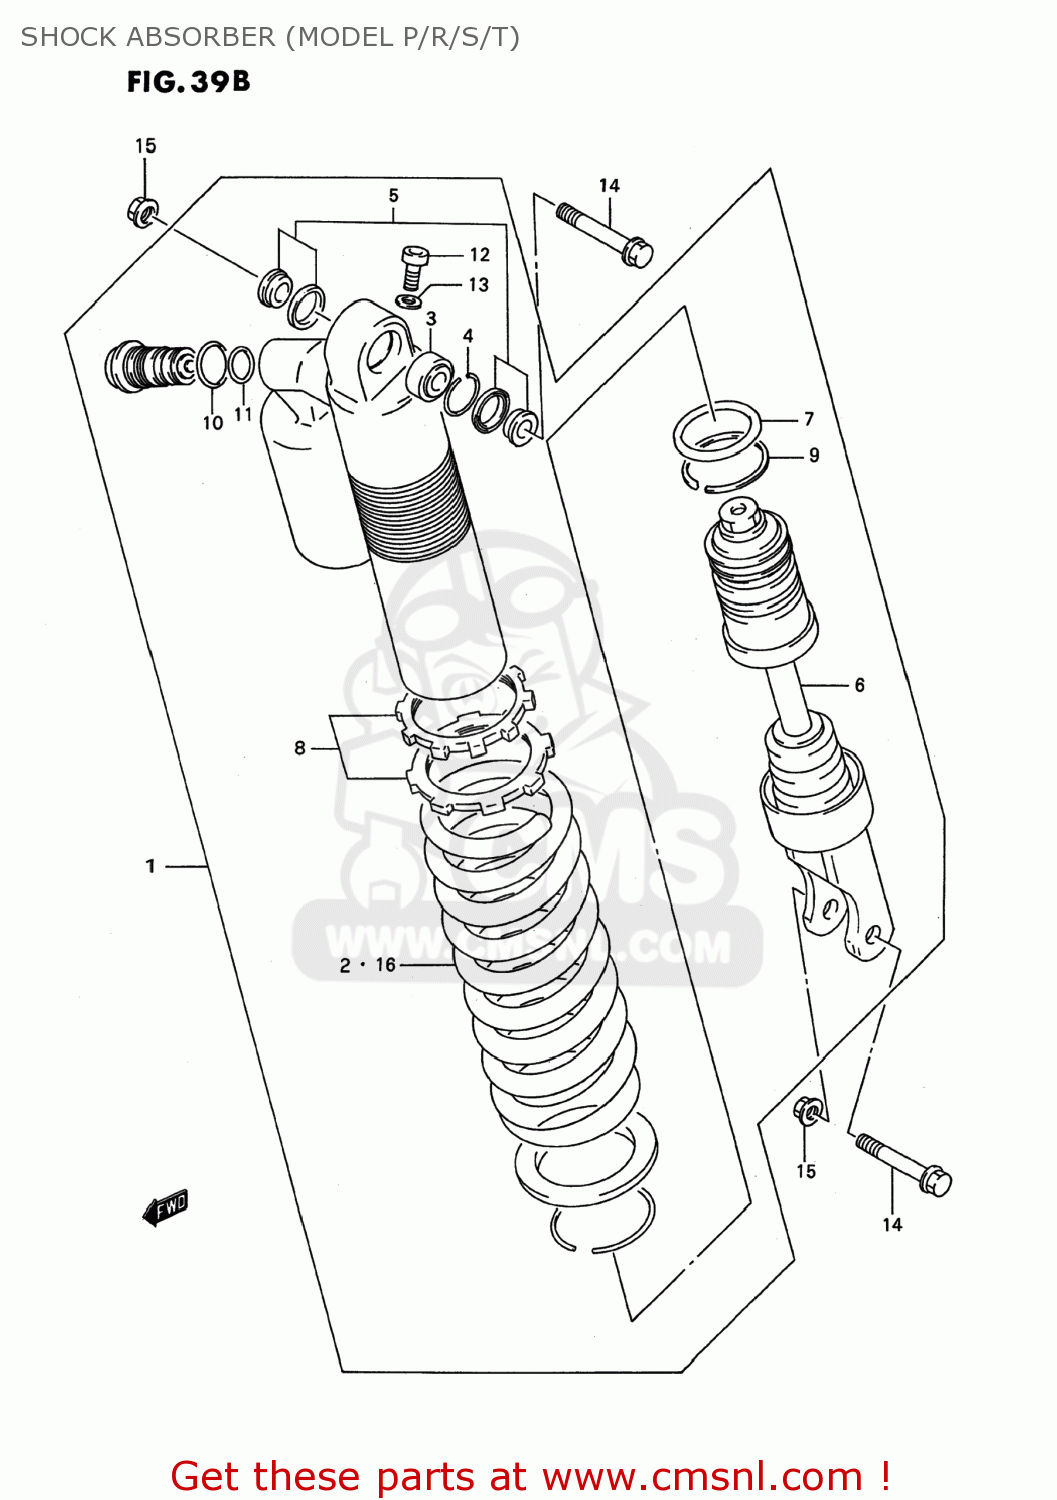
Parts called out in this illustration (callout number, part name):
1	ABSORBER ASSEMBLY,REAR SHOCK
2	SPRING
3	BEARING,RR CUSHION LEVER RR
4	RING,STOPPER
5	COLLAR SET,RR SHOCK ABSORBER
6	ROD,PISTON
7	O RING
8	ADJUSTER SET,SHOCK ABSORBER
9	RING,STOPPER
10	O RING
11	O-RING,FORK BOLT,LOWER
12	BOLT
13	GASKET,DRAIN,PLUG (NAS)
14	BOLT,REAR SHOCK ABSORBER
15	NUT
16	SPRING,REAR (K=5.4)
